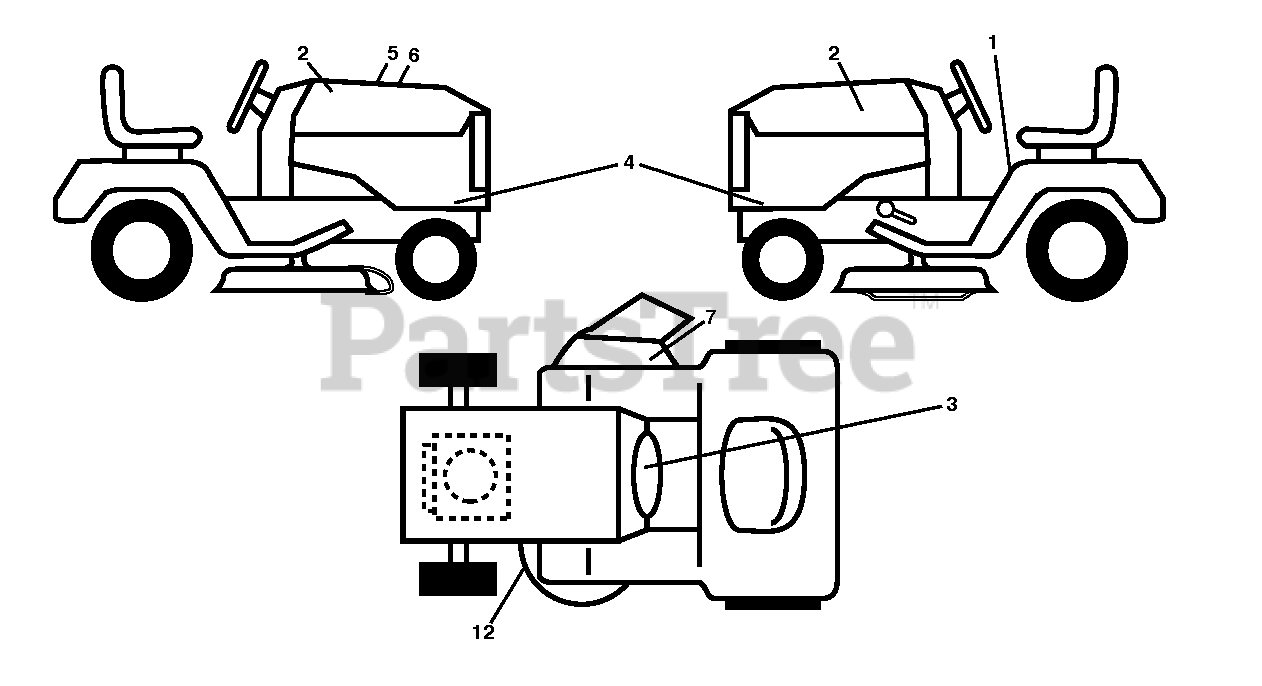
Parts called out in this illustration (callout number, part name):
1	DECAL.FENDER.WARNING.ENGLISH
2	Decal, WB 178MM 15 Husqvarna NEWBRAN
3	DECAL, WARNING SPARK ARRESTOR
4	Tractor Side Panel Decal
5	DECAL.WARNING.CUST.RESP.E85.
6	Decal, Replacement LCC 608 TLW 42
7	DECAL, DECK DEFLECTOR, WARNING
12	DECAL.V-BELT.SCH.42/46"MEC/ELE
